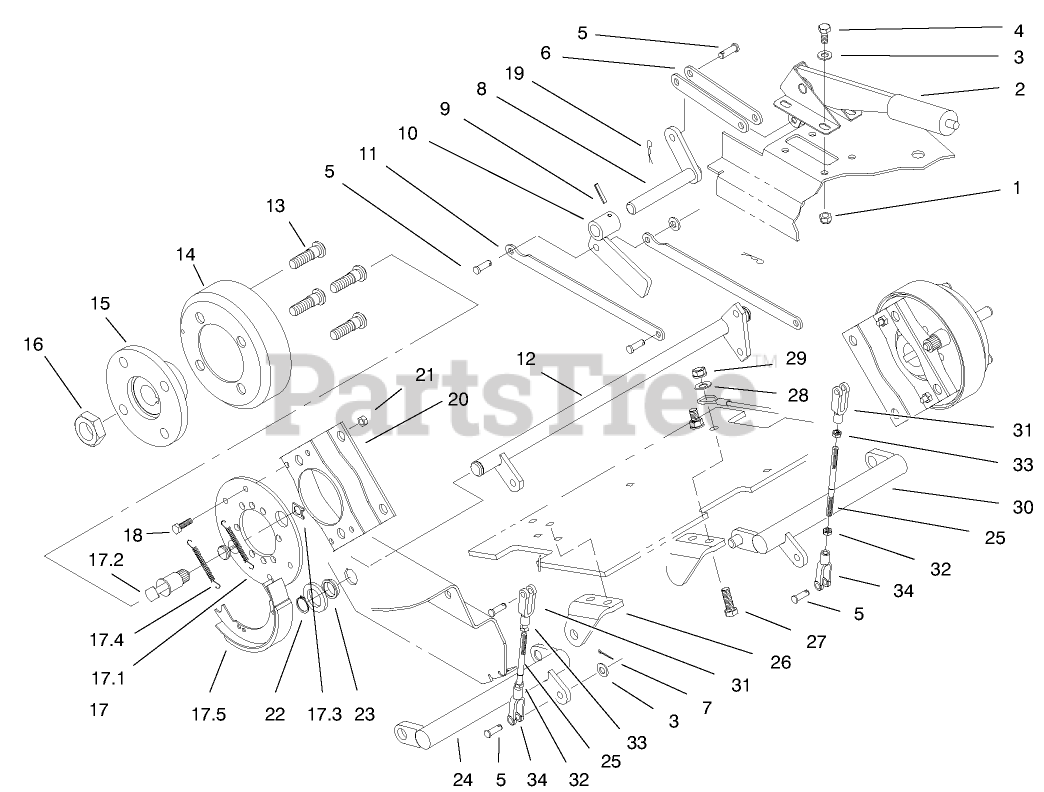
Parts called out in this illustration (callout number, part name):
1	NUT-LOCK, NI
2	LEVER-BRAKE
3	WASHER-PLAIN
4	SCREW-HH
5	PIN-CLEVIS
6	LINK-BRAKE
7	PIN-COTTER
8	TRANSFER SHAFT ASM
9	PIN-SPIRAL
10	BRAKE HUB ASM
11	LINK - CONNECT
12	TORSION SHAFT ASM
13	STUD-DRIVE
14	DRUM-BRAKE
15	Hub-Wheel
16	NUT-LOCK
17	BrakeASM
17.1	PLATE-BACKING
17.2	Cam Shaft
17.3	Clip
17.4	SPRING-RETURN
17.5	SHOE-BRAKE
18	SCREW-HH
19	PIN-COTTER
20	Bracket-Brake
21	NUT-LOCK, NI
22	Ring-Snap
23	BUSHING
24	RH BRAKE LEVER ASM
25	ROD-BRAKE
26	MOUNT-LEVER, BRAKE, RH
27	SCREW-HH
28	WASHER-FLAT
29	NUT-LOCK, NI
30	LH BRAKE LEVER ASM
31	YOKE
32	NUT-JAM
33	NUT-JAM
34	CLEVIS-ADJUSTABLE
35	WASHER-FLAT
